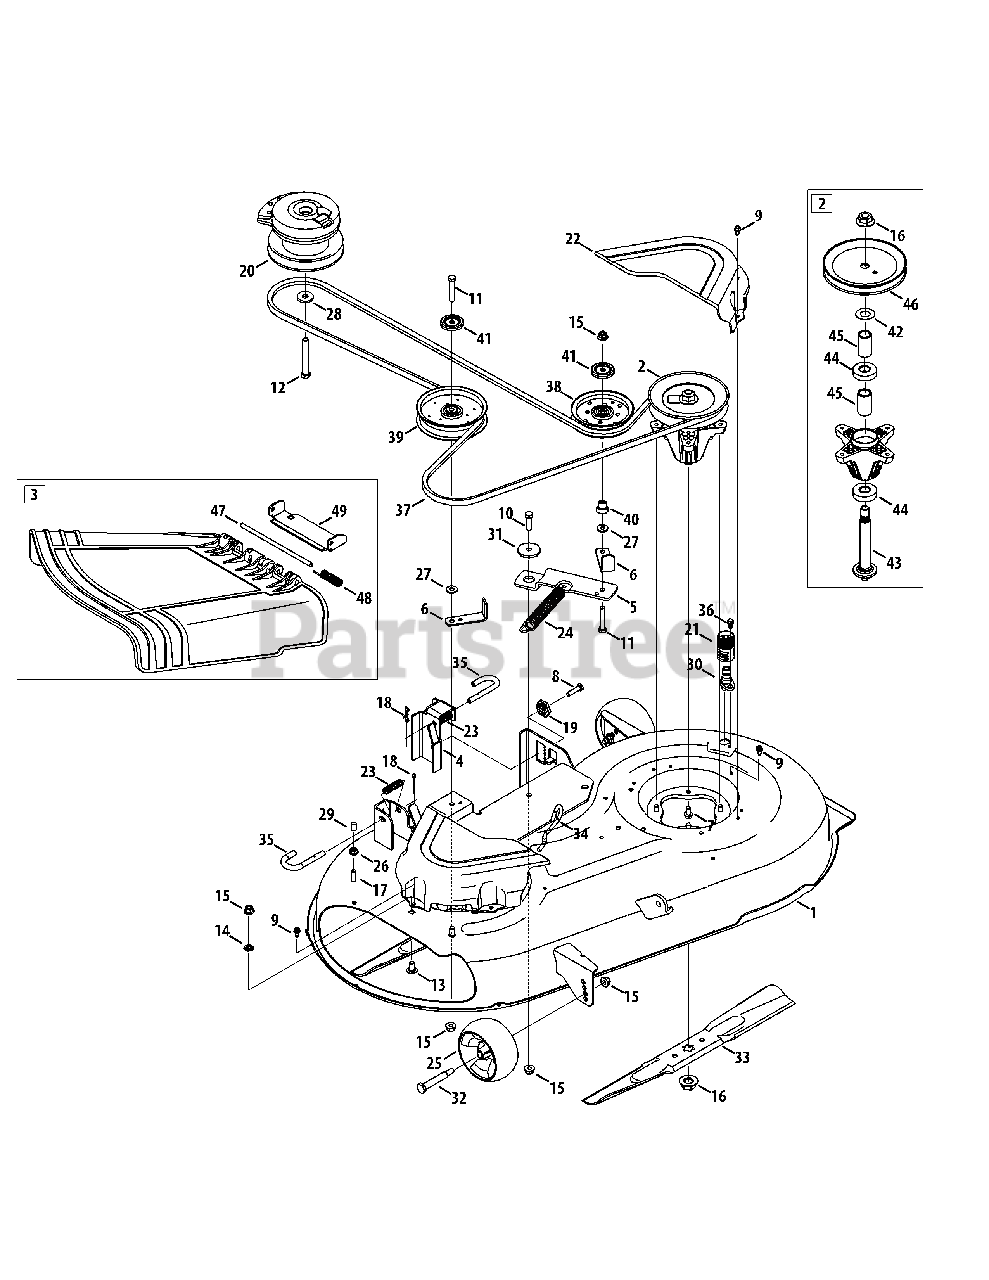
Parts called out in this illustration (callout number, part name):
1	42" Deck
2	Spindle Assembly
3	Chute Deflector Assembly
4	Deck Lift Bracket
5	Pivot Idler Bracket
6	Bracket Belt Guard
7	Hex Washer Screw, 5/16-18 x .750
8	Hex Cap Screw, 5/16-18 x 1.25
9	Hex Washer Screw, 1/4-20 x .625
10	Hex Cap Screw, 3/8-16 x 1.25
11	Hex Cap Screw, 3/8-16 x 2.00
12	Screw, 7/16-20 x 3.25
13	Carriage Screw, 3/8-16 x .75
14	Push Nut, 3/8
15	Flange Lock Nut, 3/8-16
16	Hex Flange Nut, 5/8-18
17	Hex Cap Screw, 5/16-18 x 1.00
18	Cotter Pin, 5/32 x 1.25
19	Deck Adjustment Gear
20	Electric PTO Clutch
21	Water Nozzle Adapter
22	Belt Cover
23	Compression Spring, .66 x 1.9
24	Extension Spring, .94 Dia. x 7.57
25	Deck Ball Wheel, 5.0
26	Flange Lock Nut, 5/16-18
27	Flat Washer, .385 x .870 x .092
28	Flat Washer, .450 x 1.25 x .164
29	Cap, .290 x .500
30	Deck Wash Nozzle
31	Shoulder Spacer, .884 x .190
32	Shoulder Screw, .5 x 2.5 x 3/8-16
33	Blade, 2 in 1, 21.23
34	Deck Spring Rod
35	Deck Hanger Rod
36	Shoulder Screw, .500 x 1/4-20
38	Idler Pulley, 4.25 Dia.
39	Idler Pulley, 5.00 Dia.
40	Shoulder Spacer
41	Pulley Cap
42	Washer, .760 x 1.50 x .030
43	Spindle Shaft
44	Ball Bearing
45	Spacer, .792 x 1.060 x 1.860
46	Deck Pulley
48	Torsion Spring
49	Chute Bracket
